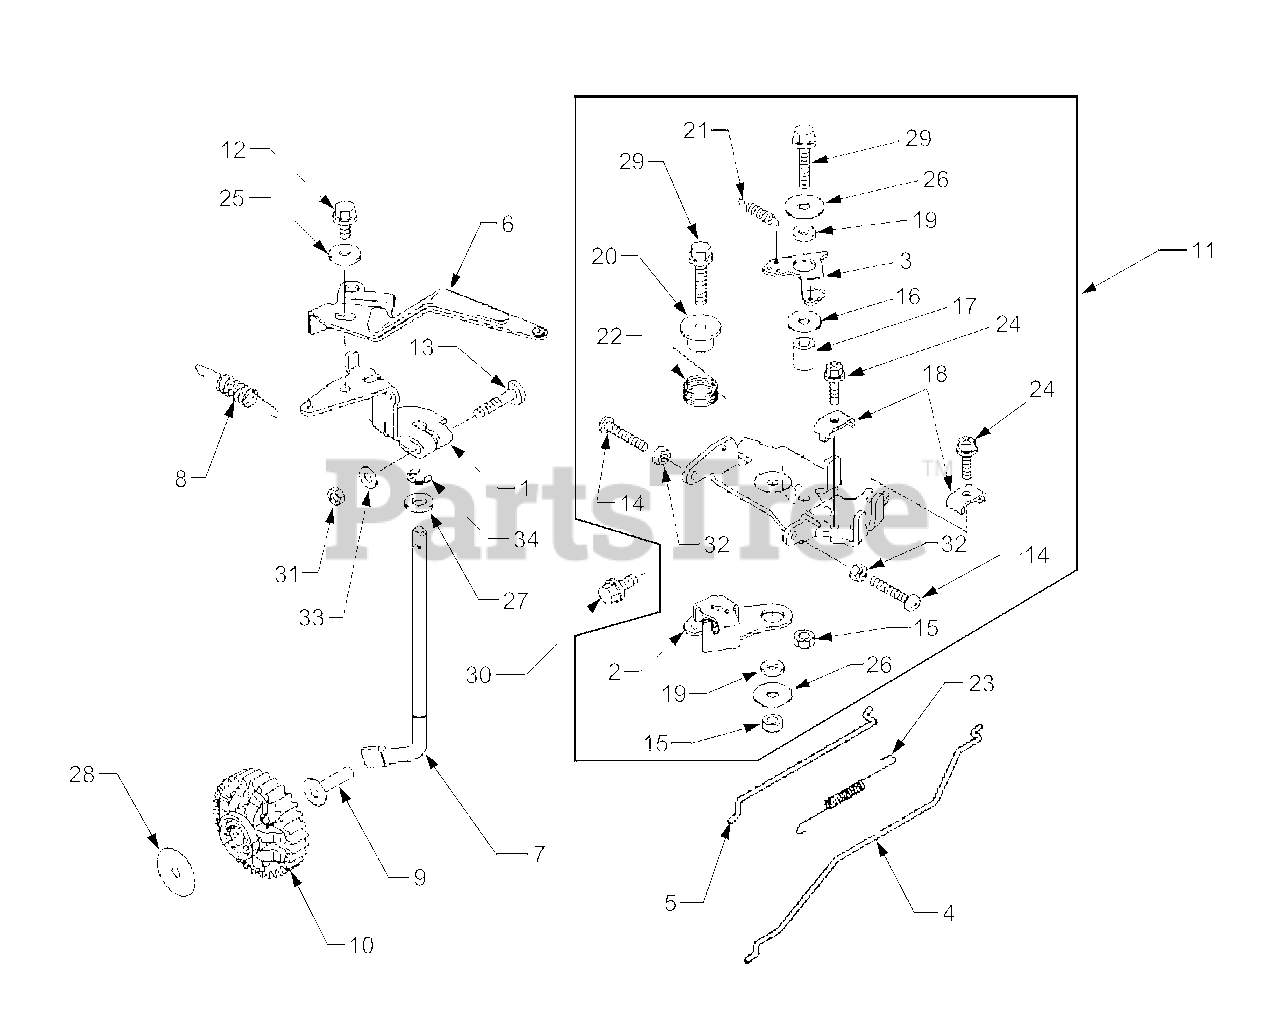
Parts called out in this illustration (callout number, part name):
2	Lever, Throttle
6	Arm Assembly
7	Arm, Governor Pivot
8	Spring, Governor
10	Gear Assembly, Governor
11	Panel, Control Complete
12	Bolt
14	Screw, 5 x 30
16	Washer, 6 x 19 x 1.2
19	Collar, 6 x 13 x 2.3
26	Washer, 6.5 x 22 x 1.2
27	Washer, 8.3 x 16 x 2.3
28	Washer, 6.2 x 30 x 0.5
29	Bolt, Flanged
30	Bolt, Flanged
31	Nut, Hex
33	Washer, Plain
34	Circlip, E-Ring
